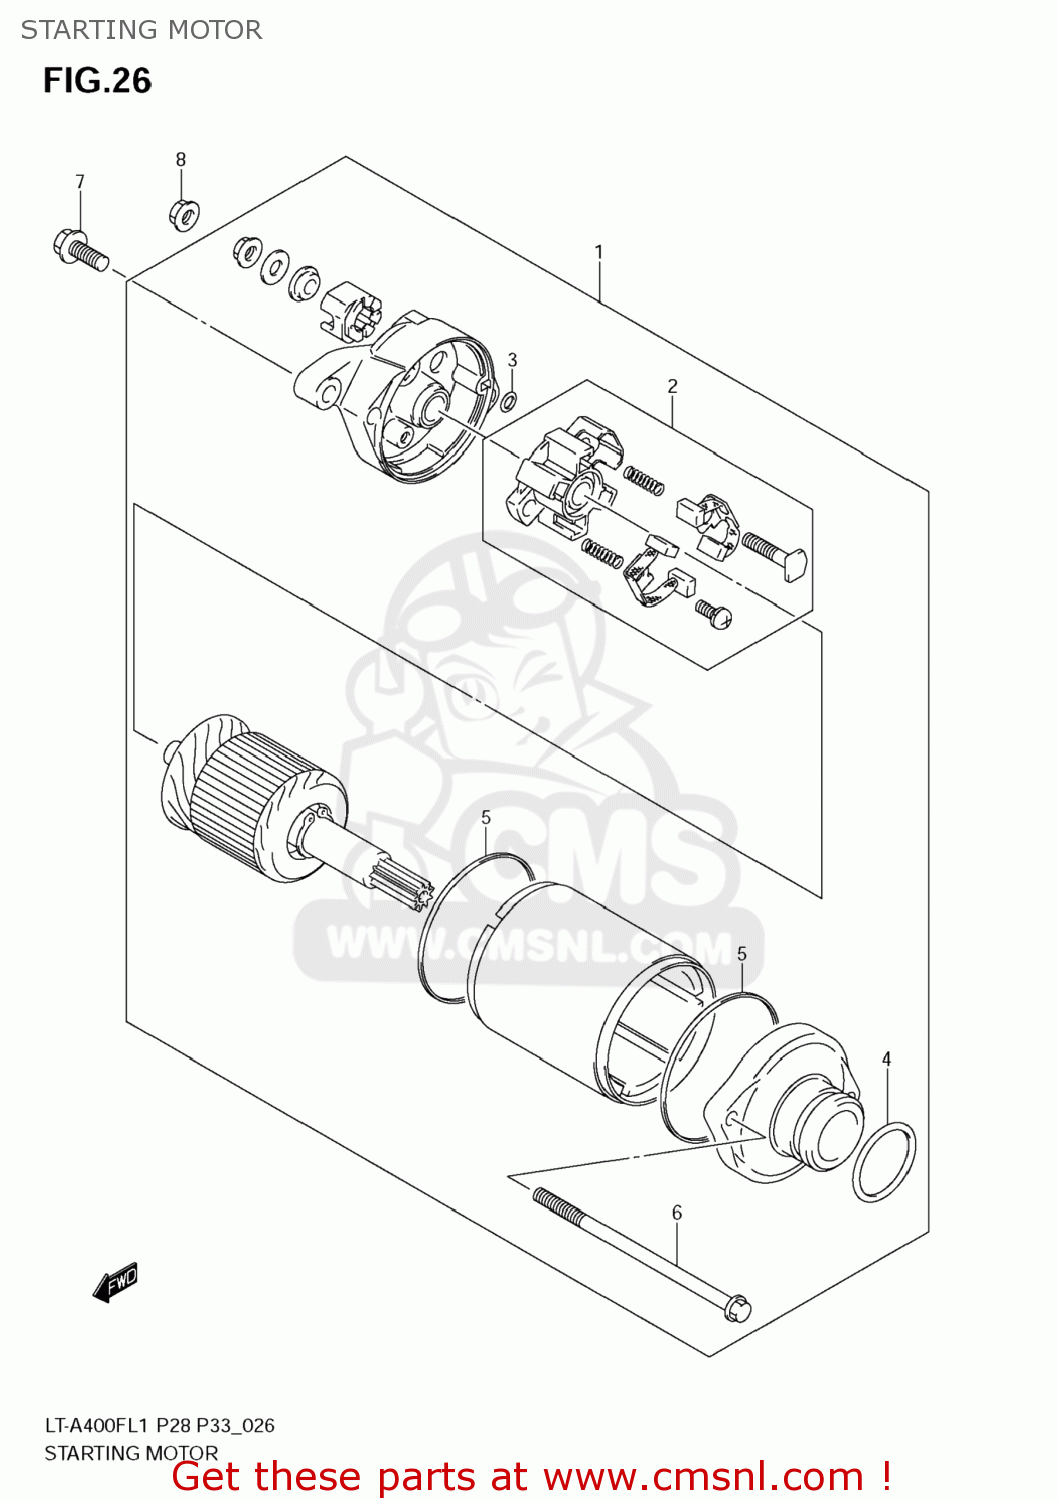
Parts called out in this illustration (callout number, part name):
1	MOTOR ASSY,STARTING
2	BRUSH HOLDER SET
3	O RING
4	O RING
5	SQUARE RING
6	BOLT
7	BOLT(6X25)
8	NUT
